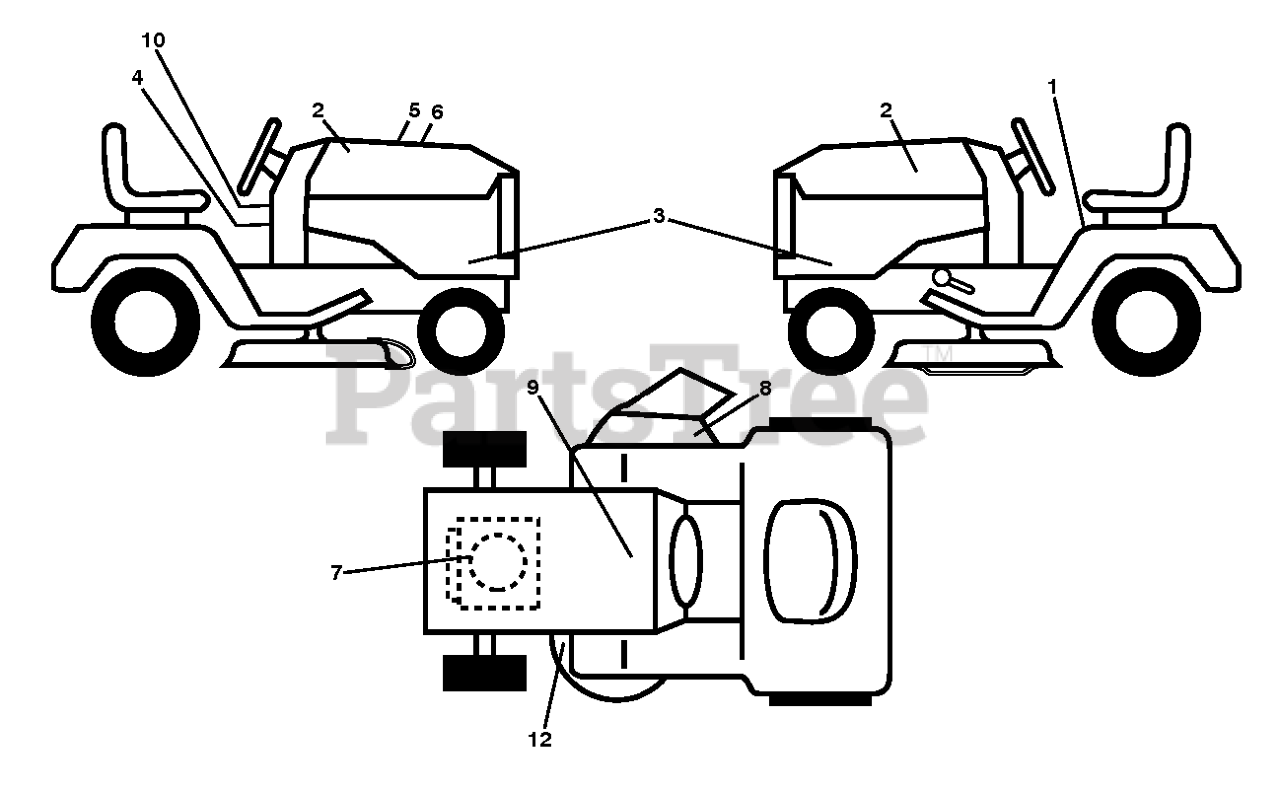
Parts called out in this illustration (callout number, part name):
1	DECAL.FENDER.WARNING.ENGLISH
2	RP.DECAL.BADGE.170MM.TEXTLOGO
3	DECAL.SIDE.PANEL.YTH22V46.2013
4	DECAL, WARNING SPARK ARRESTOR
5	DECAL.WARNING.CUST.RESP.E85.
7	DECAL.ENG.BS.22HP.INTK
8	DECAL.MOWER.WARN.KEEP.HAND.AWY
9	DECAL BTRY SYMBOLS
10	LABEL.EMISS.CALIF.HUSQVARNA
12	DECAL.V-BELT.SCH.42/46"MEC/ELE
